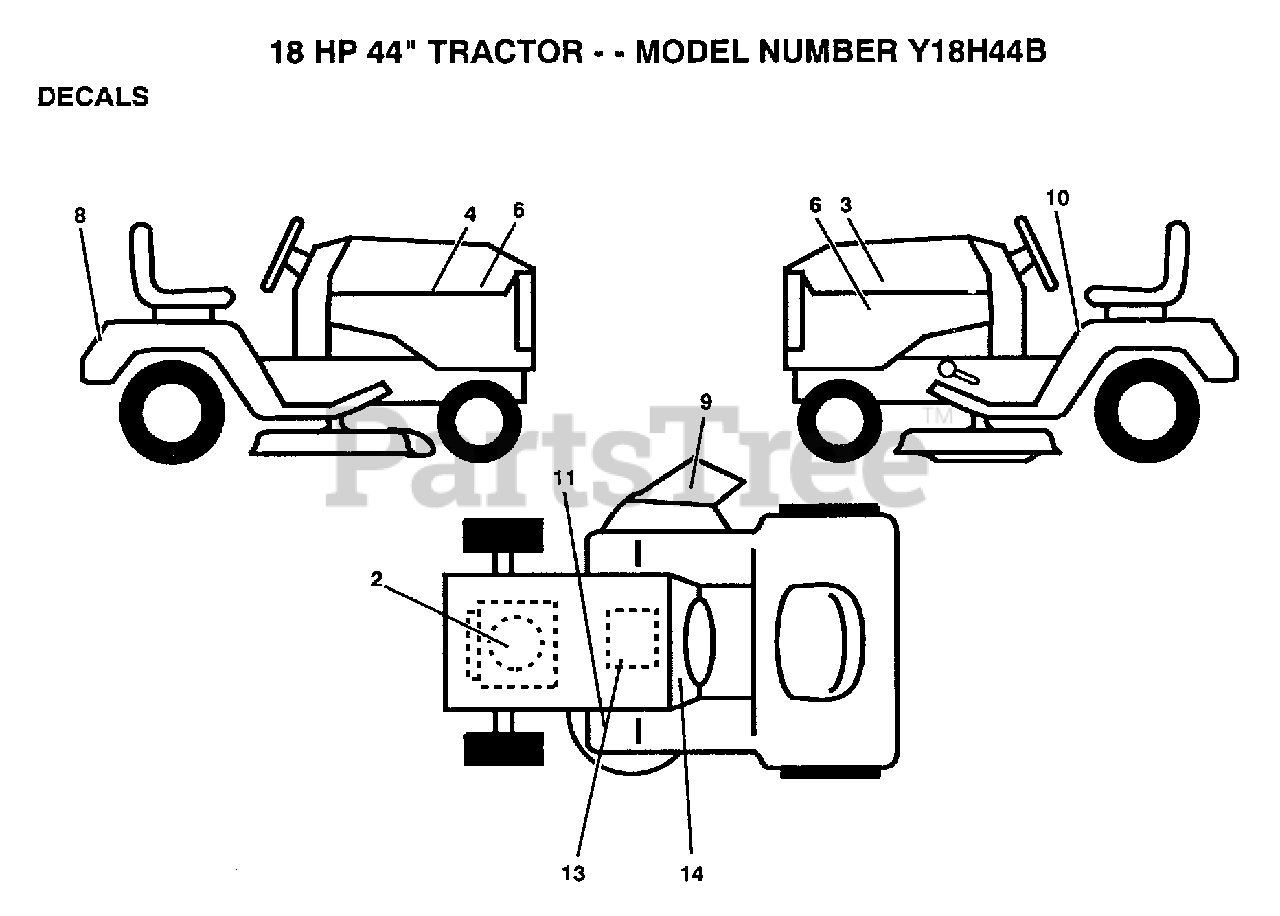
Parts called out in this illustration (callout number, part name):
2	"DECAL,HP ENGINE"
3	DECAL HOOD LH
9	DECAL WARNING
10	DECAL CAUTION
11	DECAL T
13	DECAL
